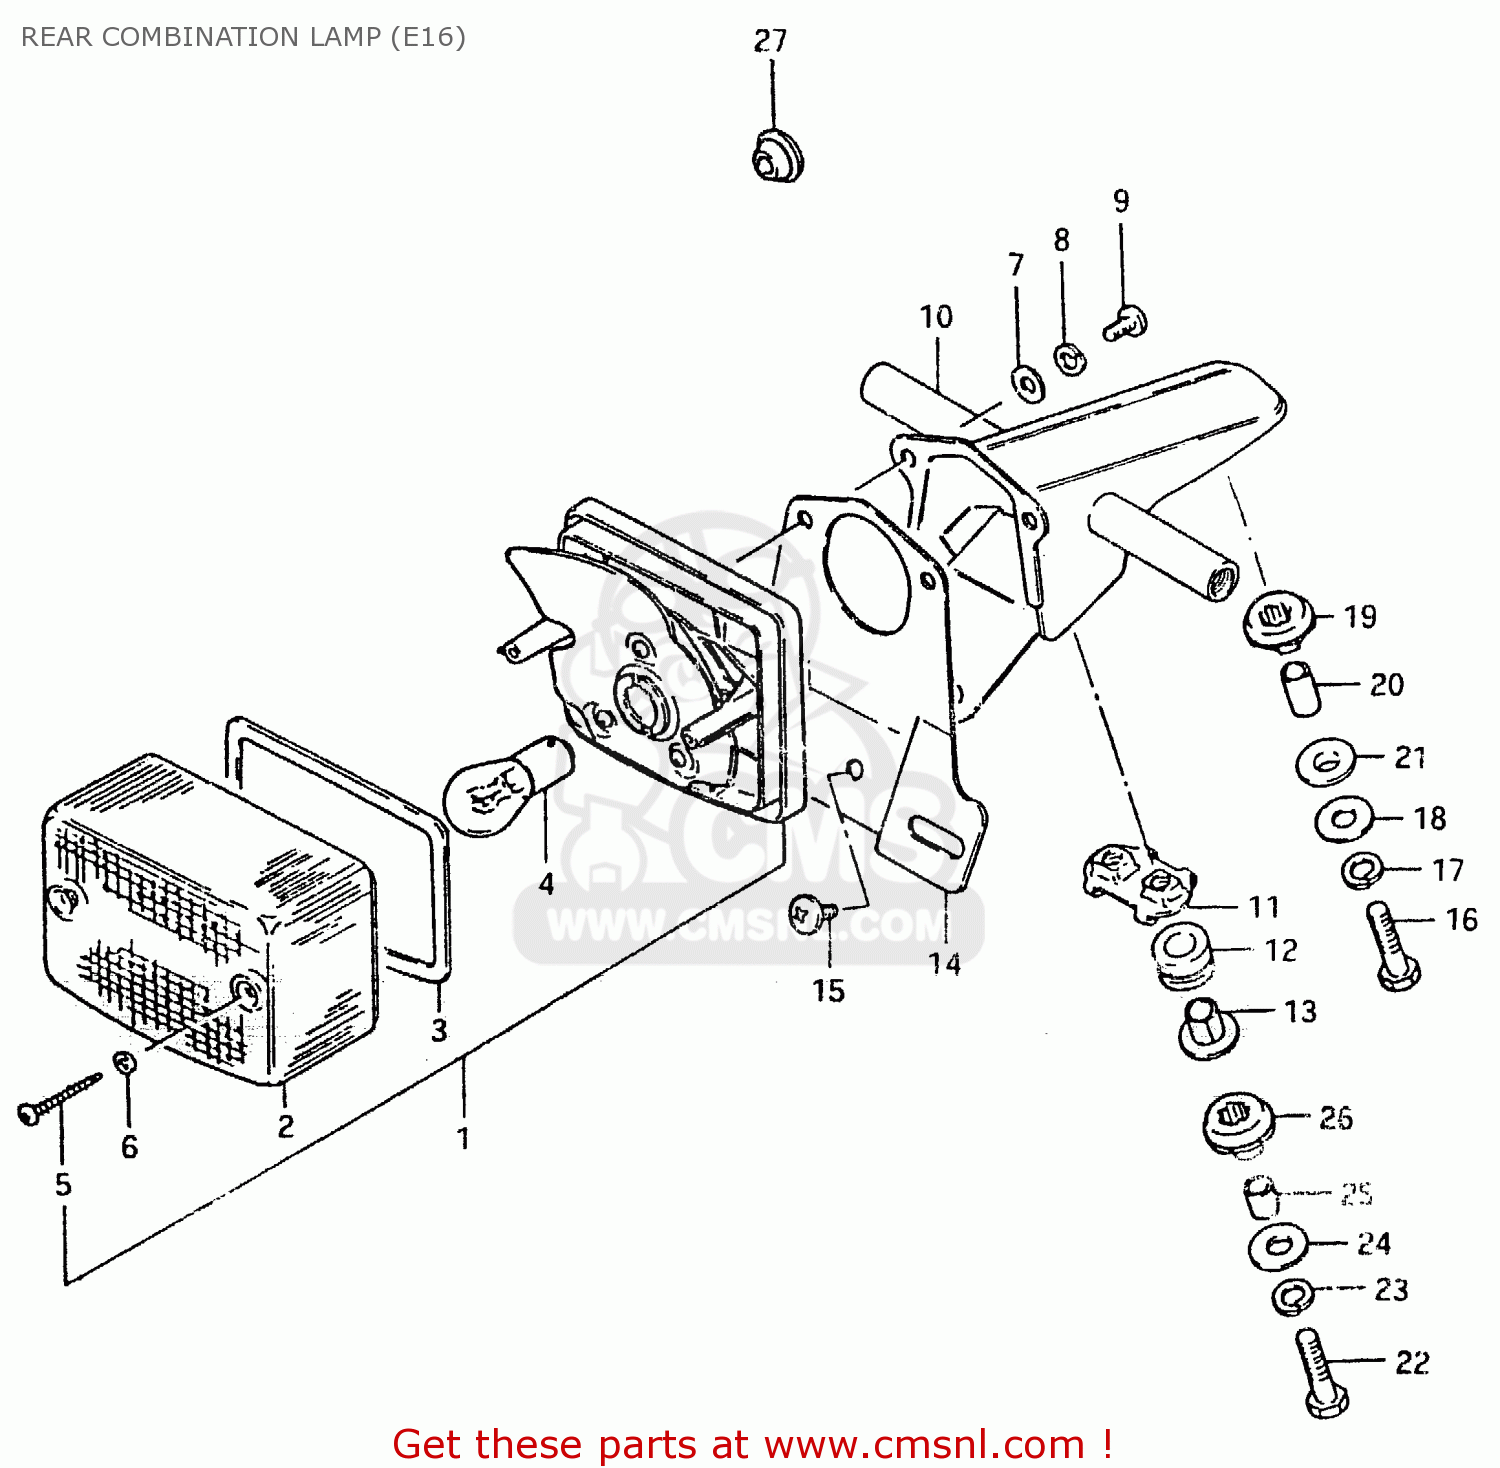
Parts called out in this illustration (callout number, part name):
1	LAMP UNIT, TAIL
2	LENS
3	GASKET (NAS)
4	BULB (6V,21/5W)
5	SCREW
6	GASKET (NAS)
7	WASHER
8	LOCK WASHER
9	SCREW
10	BRACKET ASSY
11	PLATE
12	CUSHION
13	SPACER
14	PLATE, LICENSE
15	SCREW
16	BOLT
17	LOCK WASHER
18	WASHER (6.5X20X1.2)
19	CUSHION
20	SPACER
21	CUSHION
22	BOLT 6X40
23	LOCK WASHER
24	WASHER (6.5X20X1.2)
25	SPACER (6.8X10X11.5)
26	CUSHION
27	GROMMET
